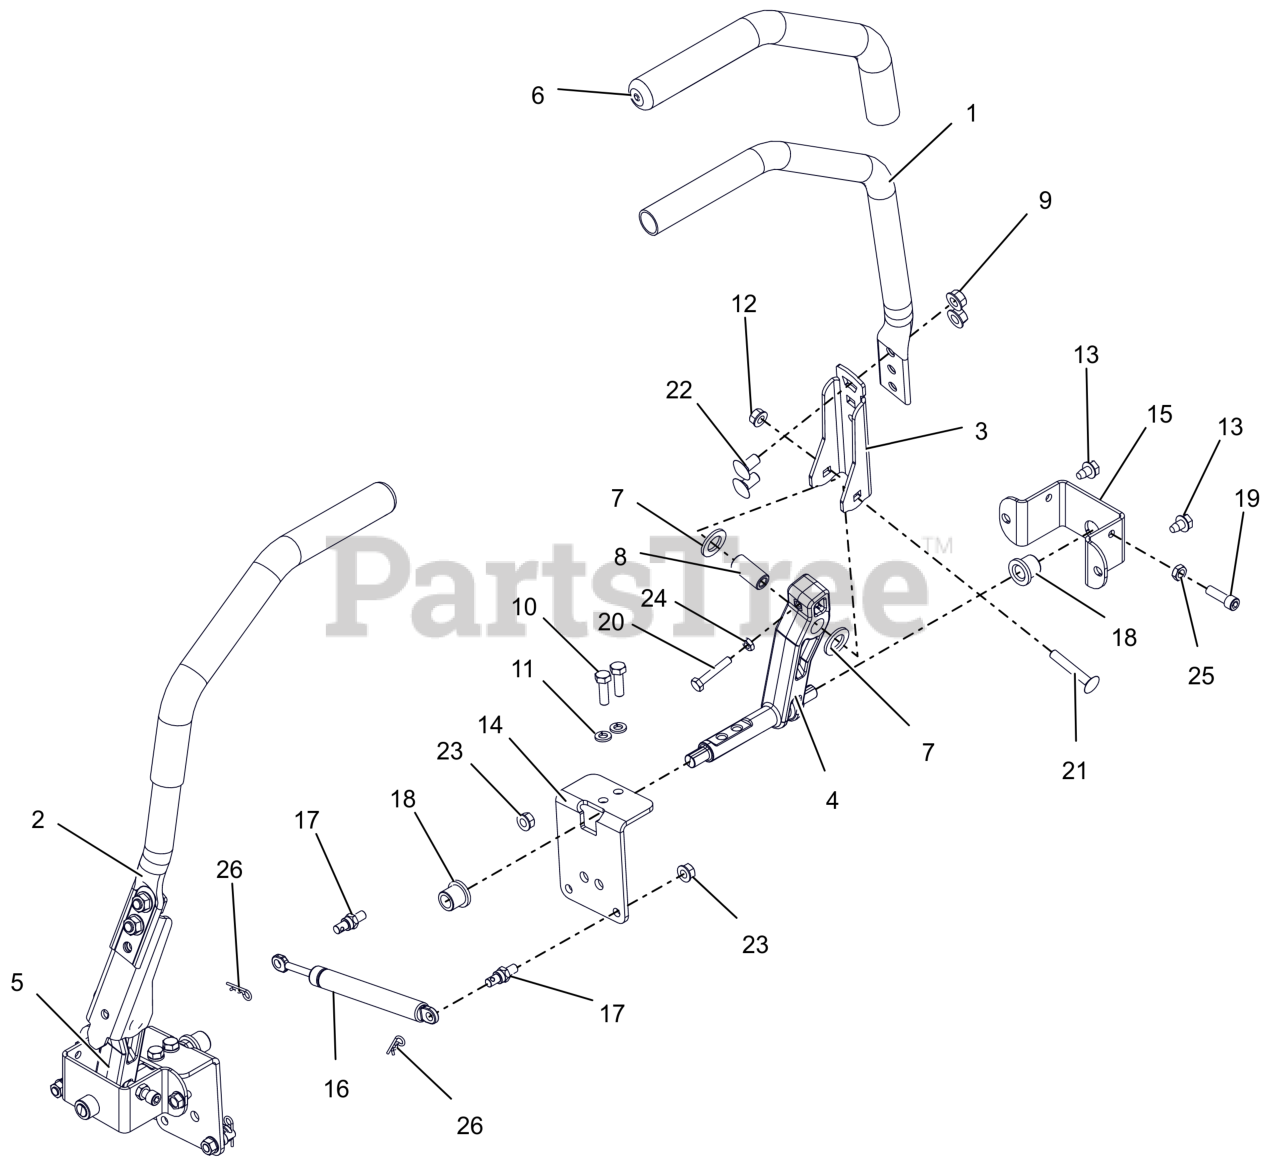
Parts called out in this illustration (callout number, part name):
1	HANDLE, STEERING-LH
2	HANDLE, STEERING-RH
3	ARM, CONTROL UPPER
4	STEERING, LH LWR CAST ARM
5	STEERING, RH LWR CAST ARM
6	GRIP, HANDLEBAR 15" FOAM
7	WSHR, FRICTION
8	BSHG-SLV .342 X .627 X 1.331
9	NUT-LK-CTR-FLG .375-16 GF ZCC
10	BLT, HEX .31-18X1.00 G8 ZCC
11	WSHR,LK-REG .312X.078 ZCC
12	NUT,LK-CTR-FLG .31-18 GF ZCC
13	SCR,TAP .312-18X.50 HWH TR ZCC
14	BRKT, STEEERING
15	BRKT, STEERING
16	DAMPER, STRAIGHT MOUNT
17	COUPLER, DAMPER MOUNT
18	BHSG-FLG .500X.750X.750X.125
19	SCR, SKH .312-18X1.00 G8 SS
20	BLT, HEX .25-20X1.50F G5 ZCC
21	BLT, RHSSN .31-18X2.00 G5 ZCC
22	BTL,RHSSN .375-16 X 0.75 G5 FPB
23	NUT-LK-TOP-FLG .312-18 GF ZCC
24	NUT-JAM .250-20 G2 ZCC
25	NUT-JAM .312-18 G2 ZCC
26	PIN, HAIR #213 .08X1.19 ZCC
